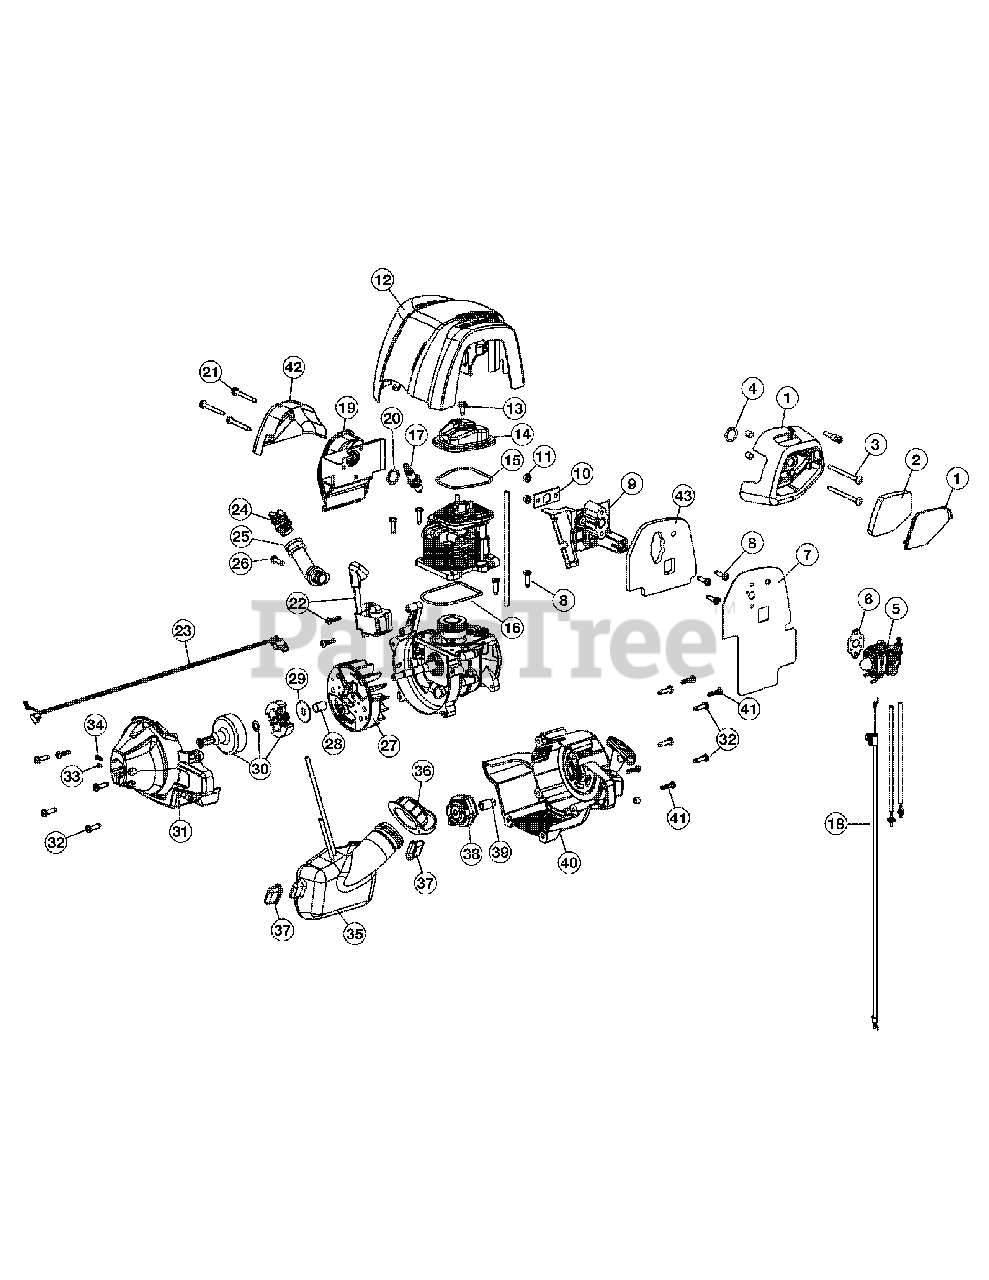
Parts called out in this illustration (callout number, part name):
1	Air Cleaner Assembly
2	Air Filter
4	Carburetor O-Ring
5	Carburetor Assembly
6	Carburetor Gasket
7	Carburetor Baffle
8	Screw
10	Insulator Gasket
12	Engine Cover
14	Valve Cover
15	Valve O-Ring
16	Cylinder O-Ring
17	Spark Plug
18	Throttle Cable
19	Muffler Assembly
20	Muffler Gasket
21	Muffler Bolt
22	Module Assembly
23	Lead Wires
24	Oil Plug Assembly
25	Oil Fill Tube Assembly
29	Clutch Washer
30	Clutch Assembly
31	Clutch Cover Assembly
33	Anti Rotation Screw
34	Clamp Screw & Nut
35	Fuel Tank
37	Fuel Tank Pad
38	Pawl Assembly
39	Electric Start Adapter
40	Starter Cover Assembly
42	Muffler Shield
43	Carburetor Heat Shield
